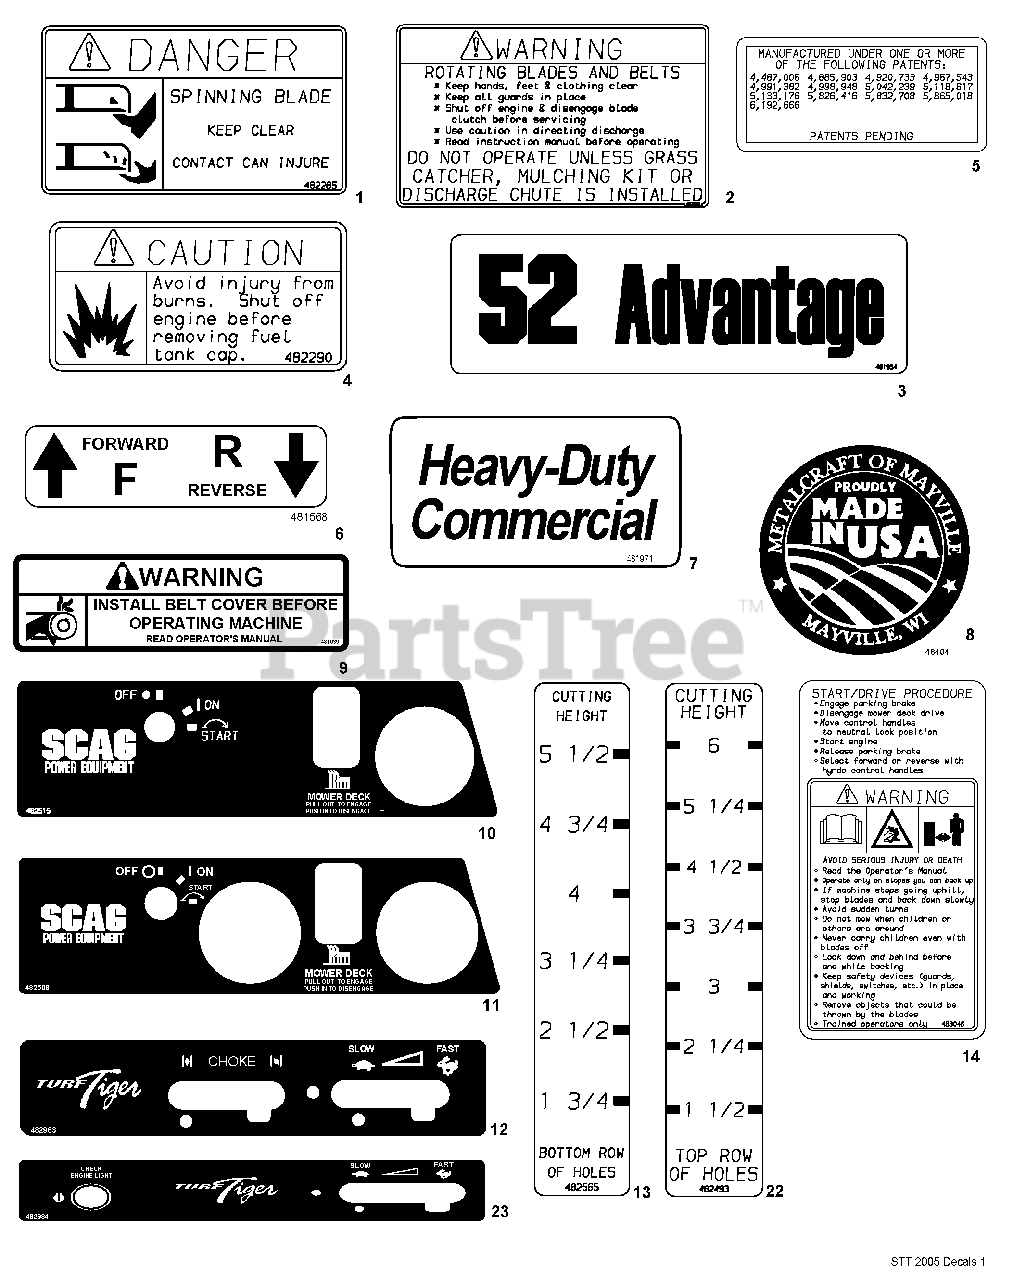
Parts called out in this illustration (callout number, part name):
1	Decal, Danger-Spinning Blades
2	Decal, Warning-Rotating Blades
3	Decal, 52 Advantage
4	Decal, Fuel Tank
5	Decal, Patents
6	Decal, Traction Control
7	Decal, Heavy Duty Commercial
8	Decal, Metalcraft-Made In USA
9	Decal, Belt Cover
10	Decal, Instrument Panel-Upper (Air Cooled)
11	Decal, Instrument Panel-Upper
12	Decal, Instrument Panel-Lower
13	Decal, Cutting Height - Lower
14	Decal, Start/Drive Procedure
22	Decal, Cutting Height - Upper
23	Decal, Instrument Panel - Lower
